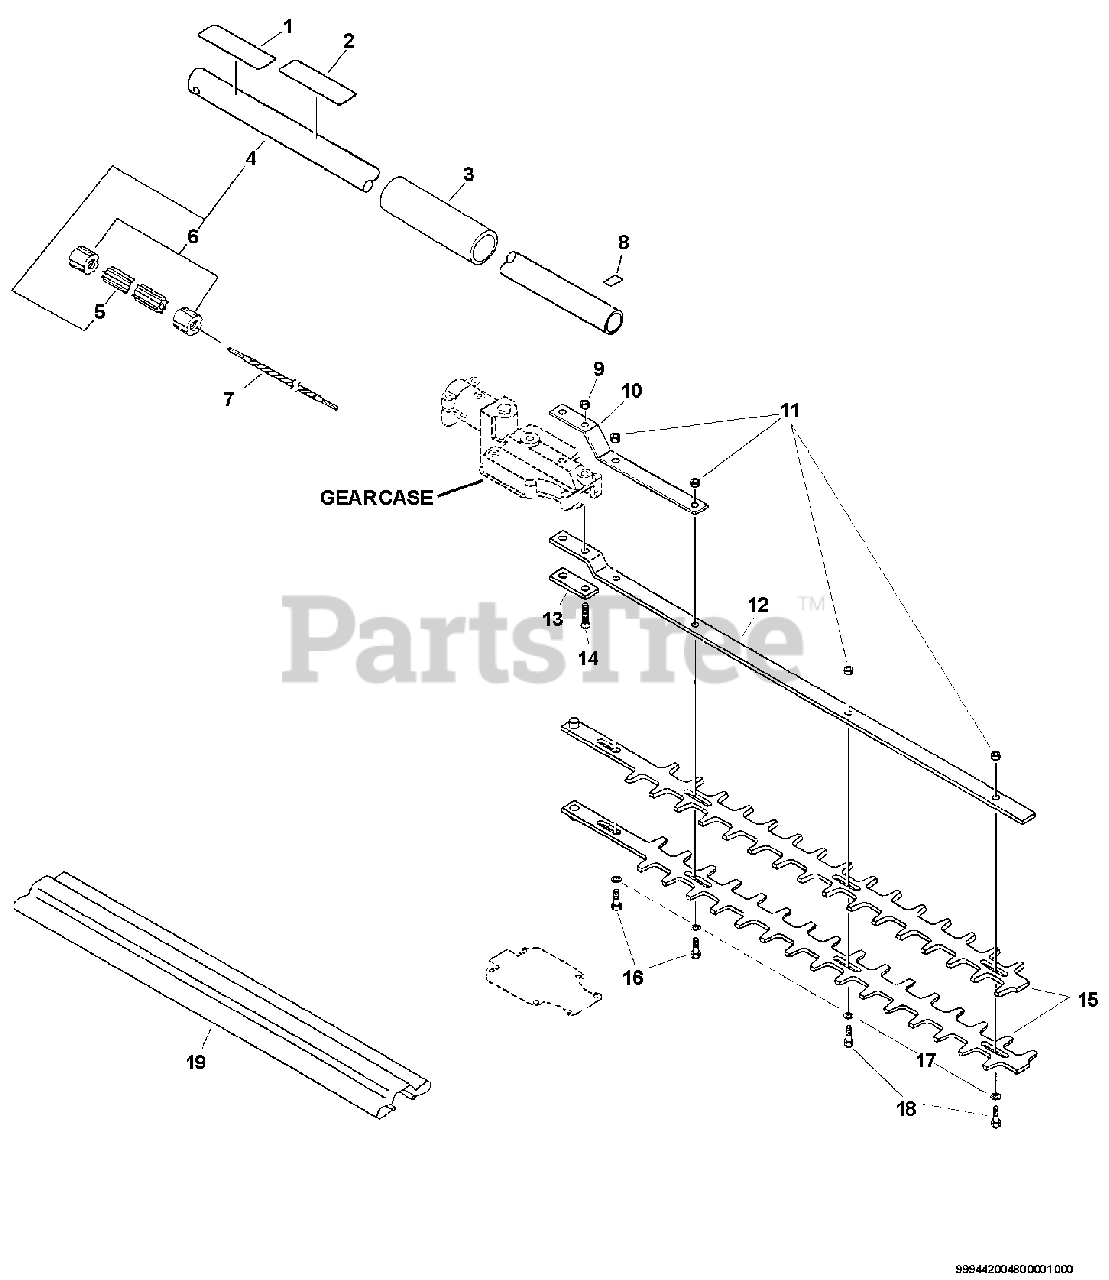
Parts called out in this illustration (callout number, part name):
1	LABEL - CAUTION
2	LABEL - CAUTION
3	GRIP, HANDLE
4	MAIN PIPE ASSY
5	LINER - FLEXIBLE
7	DRIVESHAFT - FLEXIBLE
8	LABEL - ALIGNMENT
9	LOCKNUT - 6
11	LOCKNUT - 6
12	SUPPORT, BLADE - 20" (50cm)
14	SCREW - 6X35
15	BLADE - 20" (50cm)
17	WASHER - 6
18	BOLT - 6
19	COVER, BLADE
